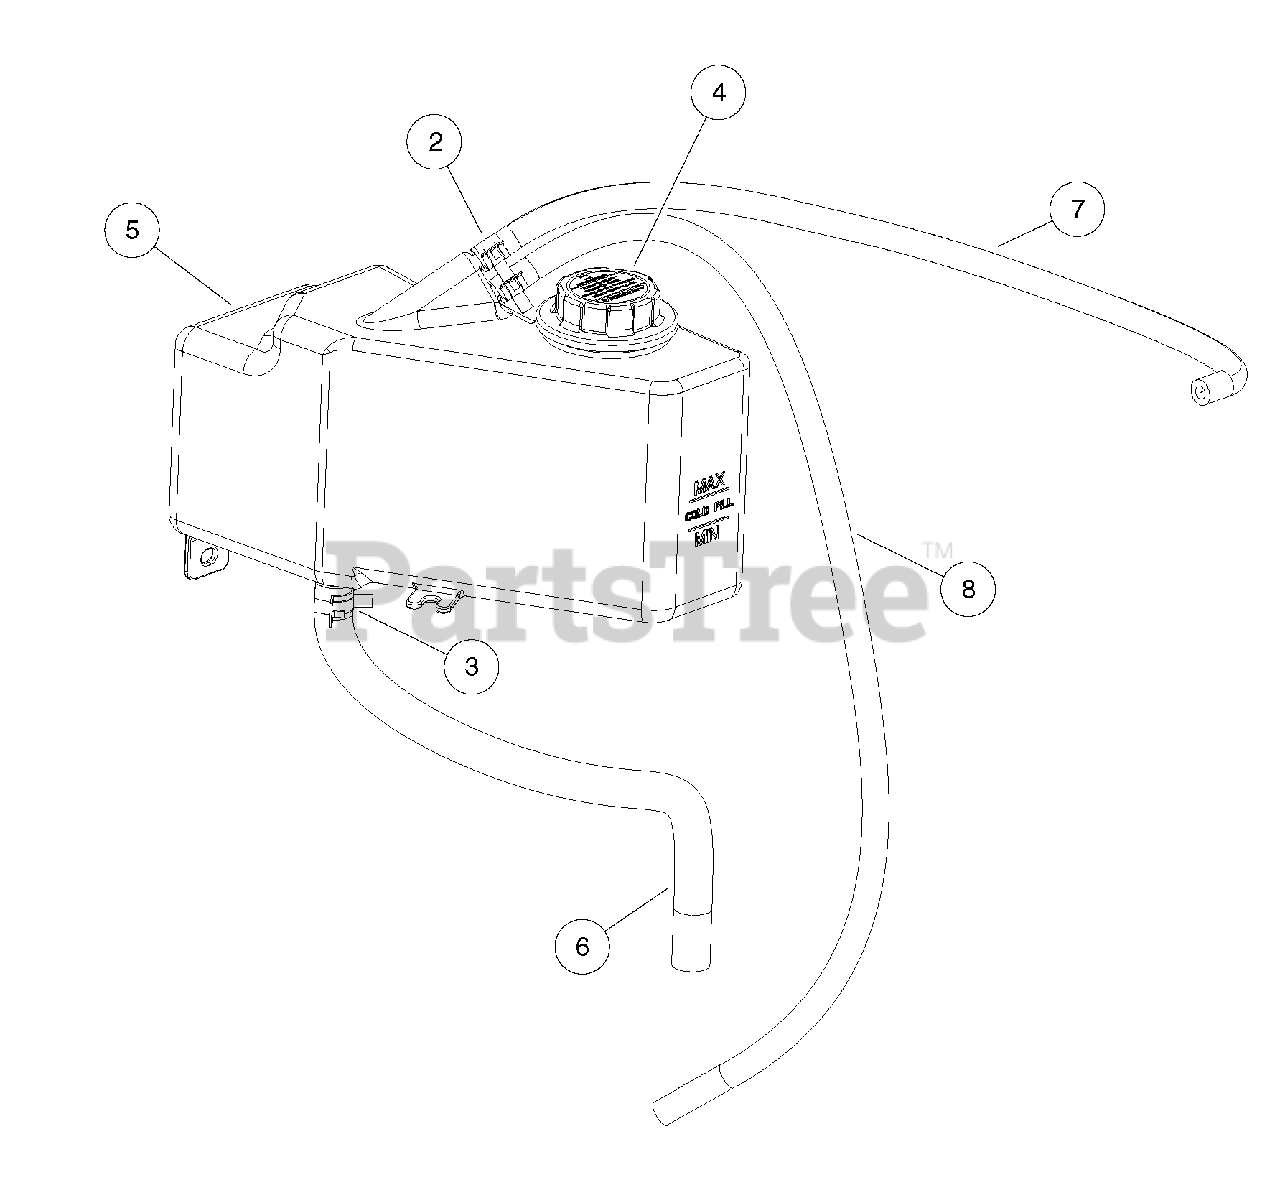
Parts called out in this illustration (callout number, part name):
1	Asm, Coolant Bottle
2	Clamp, Hose, CTB 15mm
3	Clamp, Hose, CTB 22mm
4	Cap, Radiator
5	Bottle, Coolant
6	Hose, Cut, 5/8, 445
7	Hose, Cut, Coolant, 700
8	Hose, Cut, Coolant, 1100
